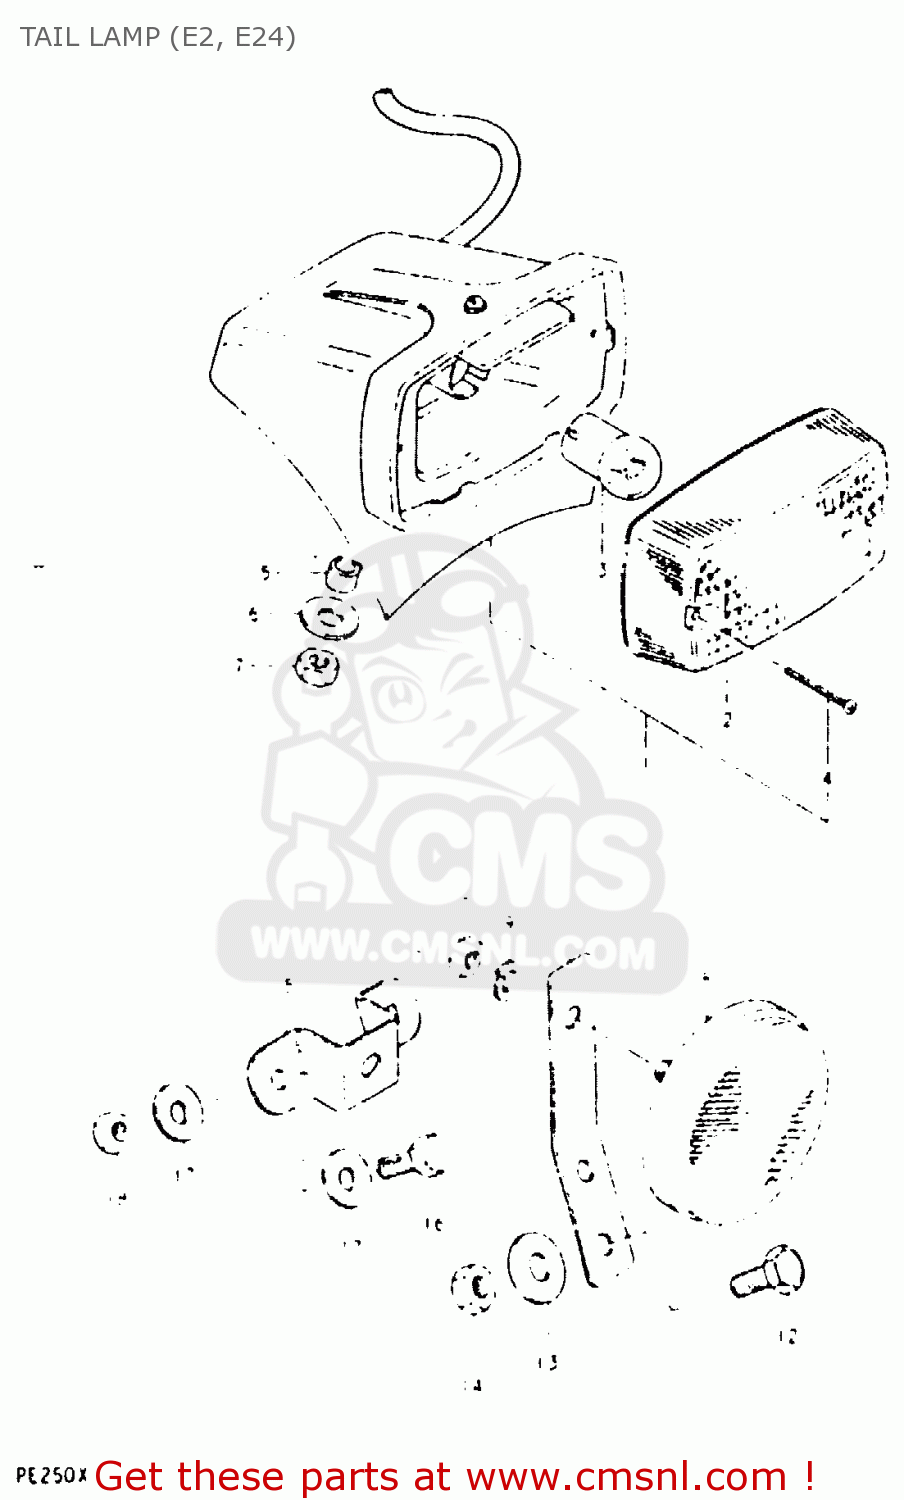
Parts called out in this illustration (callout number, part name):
1	LAMP ASSY, TAIL
2	LENS
3	BULB(6V17/5.3W,STANLEY,A4813)
4	SCREW,REAR COMBINATION LAMP LENS
5	SPACER (6.1X9X9)
6	WASHER
7	NUT
8	REFLEX REFLECTOR,RR
9	LOCK WASHER
10	NUT
11	BRACKET
12	BOLT
13	WASHER
14	NUT
15	BRACKET
16	BOLT
17	WASHER
18	NUT
